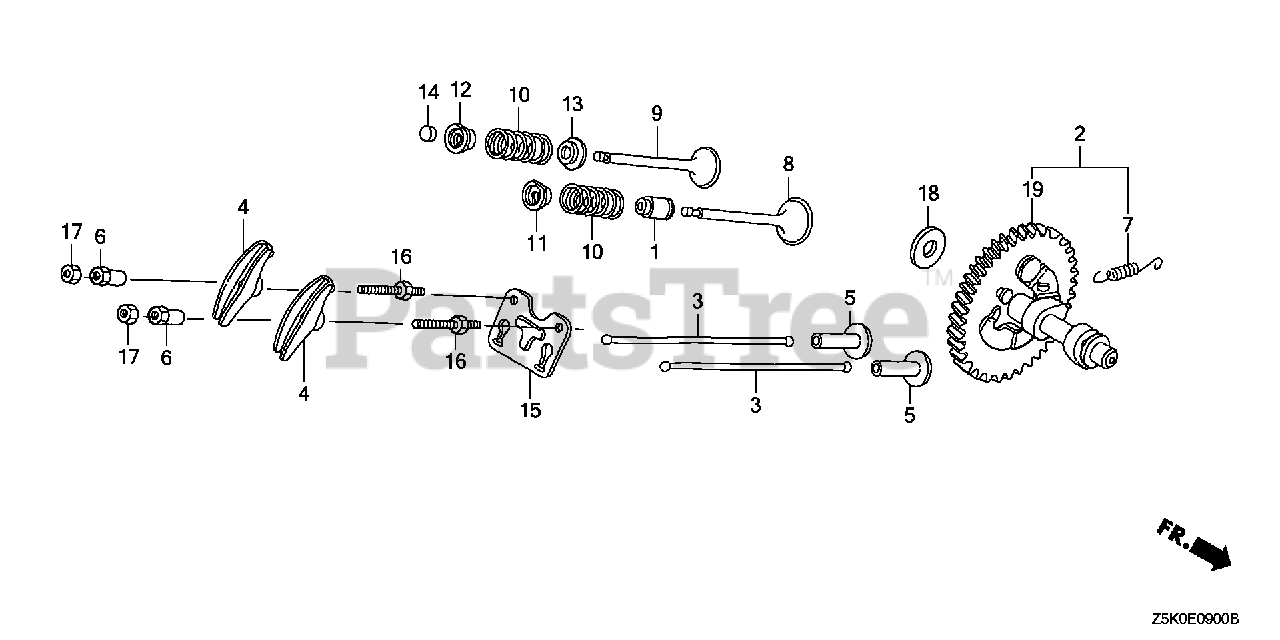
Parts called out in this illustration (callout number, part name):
1	SEAL, VALVE STEM
2	CAMSHAFT ASSY.
4	ARM, VALVE ROCKER
5	LIFTER, VALVE
6	PIVOT, ROCKER ARM
7	SPRING, WEIGHT RETURN
8	VALVE, IN.
9	VALVE, EX.
10	SPRING, VALVE
11	RETAINER, IN. VALVE SPRING
12	RETAINER, EX. VALVE SPRING
13	SEAT, VALVE SPRING
14	ROTATOR, VALVE
15	GUIDE, PUSH ROD
16	BOLT, PIVOT (8MM)
17	NUT, PIVOT ADJUSTING
